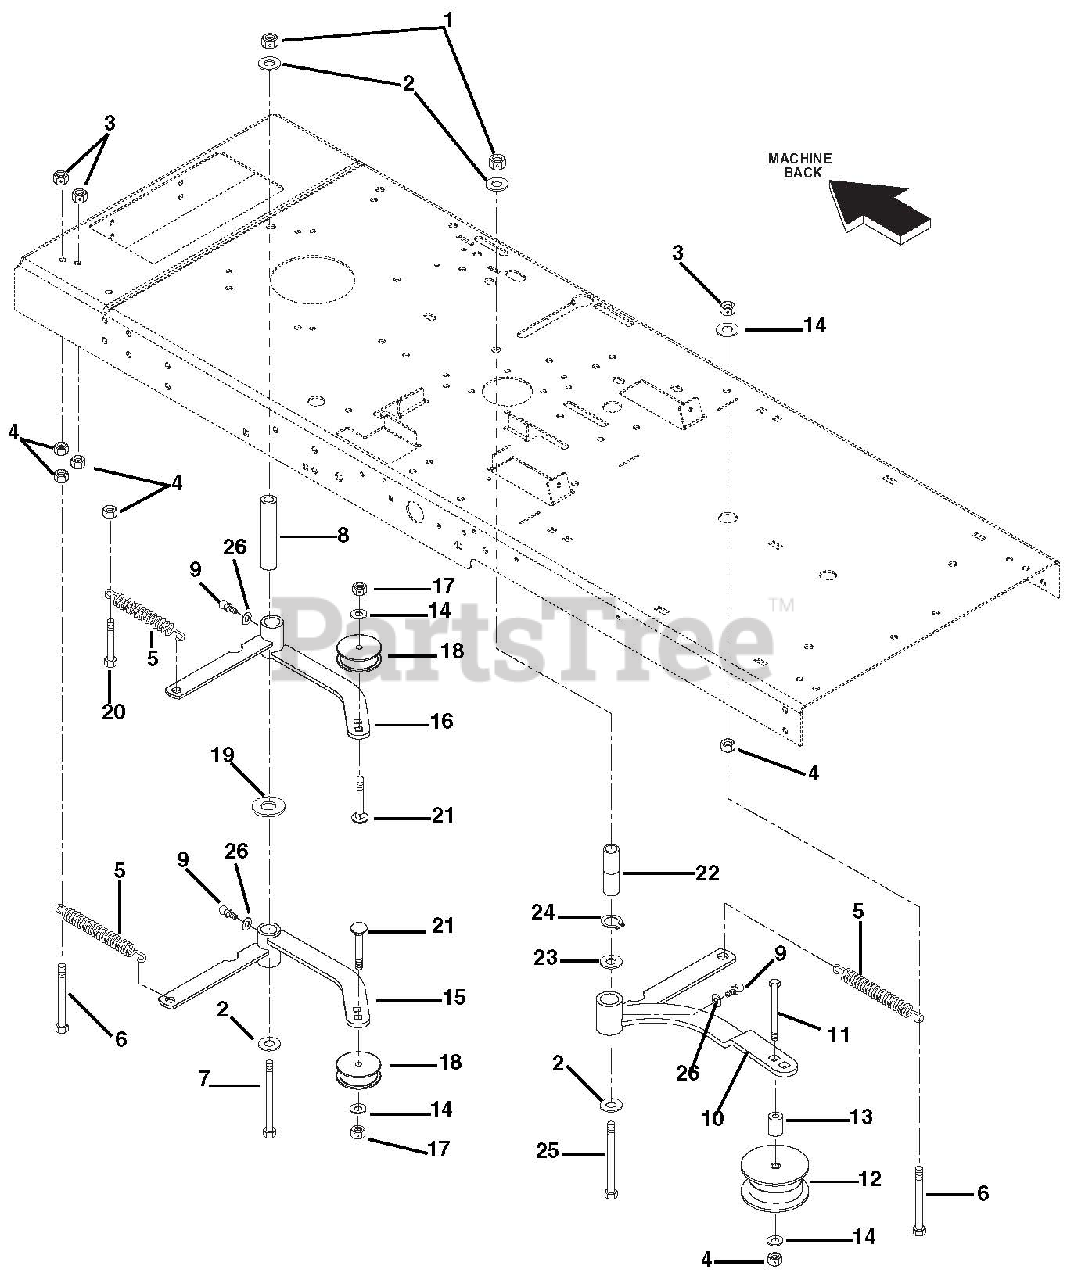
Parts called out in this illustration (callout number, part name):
1	@NUT-LK-CTR .50-13 YWZC
2	@WSHR-FL-STL.563X1.38X.109YWZC
3	@NUT-LK-CTR .38-16 YWZC
4	@NUT-HEX .38-16 YWZC
5	SPRING, EXT
6	@BLT-HEX .38-16X4.00 GR5 YWZC
7	@BLT-HEX .50-13X5.50 GR5YWZC
8	SPACER, IDLER
9	FTG-LUBE .25-28X.256 YWZC
10	WELDMENT, IDLER ARM
11	@BLT-HEX .38-16X4.50 GR5 YWZC
11	@BLT-HEX .38-16X2.50 GR5 YWZC
12	IDLER 4.0" DIA
13	SPACER, IDLER - 48"
14	@WSHR-FL-STL.406X.812X.065 YWZ
15	IDLER ARM WLDM'T TRANSAXLE
16	WLDM'T JACKSHAFT IDLER ARM
17	@NUT-LK-CTR-JAM .375-16 YWZC
18	IDLER 3.5" DIA
19	WASHER, .937 X 2.25 YWZC
20	@BLT-HEX .38-16X1.75 GR5 YWZC
21	@BLT-RDHDSQNK .38-16X1.50 G2YZ
22	SPACER, IDLER
23	WSHR-FL-STL .880X1.250X.062YWZ
24	RG-RTNG-EXT .875X.042
25	@BLT-HEX .50-13X4.50 GR5 YWZC
26	@WSHR-FL-STL.250X.56X.049 YWZC
